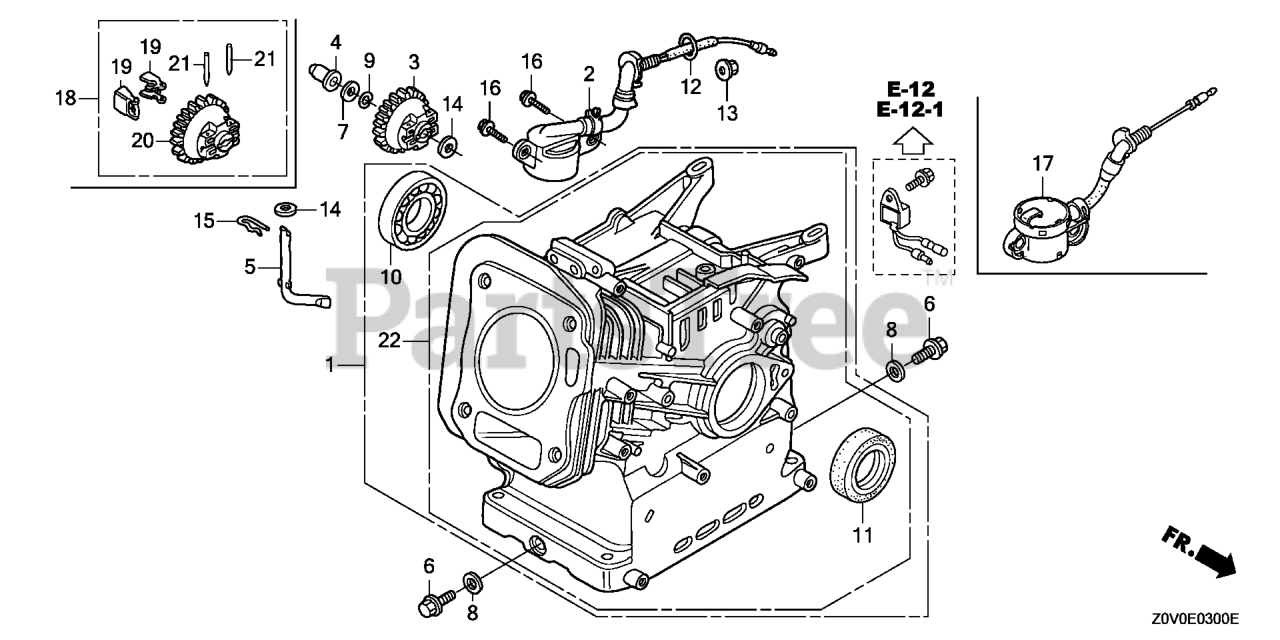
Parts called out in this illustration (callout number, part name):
3	GOVERNOR ASSY.
4	SLIDER, GOVERNOR
5	SHAFT, GOVERNOR ARM
6	BOLT, DRAIN PLUG
7	WASHER, THRUST (6MM)
8	WASHER, DRAIN PLUG (10.2MM)
9	CLIP, GOVERNOR HOLDER
11	OIL SEAL (25X41X6)
11	OIL SEAL (25X41X6) (ARAI) (NOT AVAILABLE)
12	O-RING (14MM) (ARAI) Use up to Engine SN 2949254.
13	NUT, FLANGE (10MM)
14	WASHER, PLAIN (6MM)
15	PIN, LOCK (8MM)
16	BOLT, FLANGE (6X12) Use up to Engine SN 1543277.
17	SWITCH ASSY., OIL LEVEL
22	CYLINDER ASSY. (OIL ALERT)
